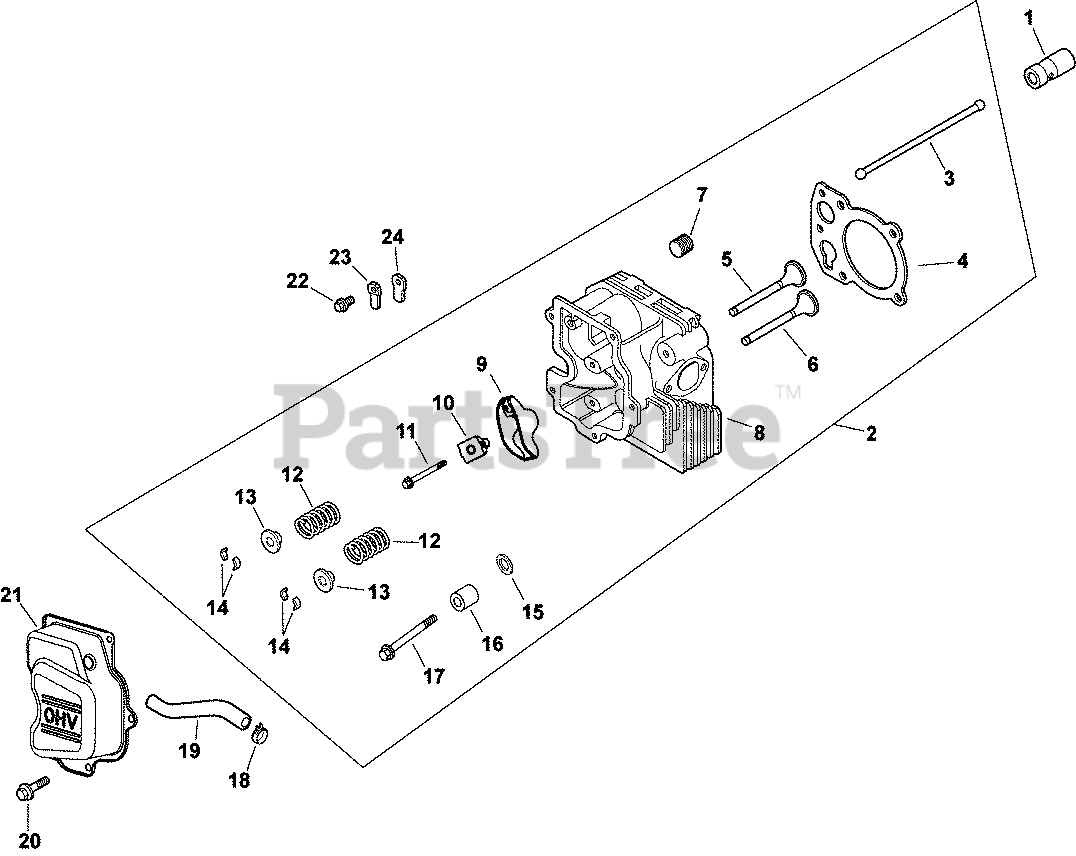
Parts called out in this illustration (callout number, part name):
1	LIFTER, HYDRAULIC VALVE-USE 25 351 10-S
2	KIT, CYLINDER HEAD
3	ROD, PUSH
4	GASKET, CYLINDER HEAD
5	VALVE, INTAKE
6	VALVE, EXHAUST
7	PLUG, CTSK PIPE 1/8"
8	KIT, HEAD, CYLINDER
9	ARM, ROCKER
10	PIVOT, ROCKER ARM
11	SCREW, FLG M6X1.0X34
12	SPRING, VALVE
13	RETAINER, VALVE SPRING - USE 25 173 28-S
14	KIT, RETAINER
15	WASHER, FLAT 13/32"
16	SPACER, HEAD BOLT EXHAUST PORT
17	SCREW, CYLINDER HEAD (M10 X 80)
18	CLAMP, HOSE (KM)-USE 25 237 31-S
19	HOSE
20	SCREW,FLG THD FRM M6X1.0X16-(#25086397S)
21	COVER, ROCKER
22	SCREW, FLG THD FRM M5X.8X10
23	RETAINER, REED
24	REED, BREATHER
1232630-S	HOSE, BREATHER
